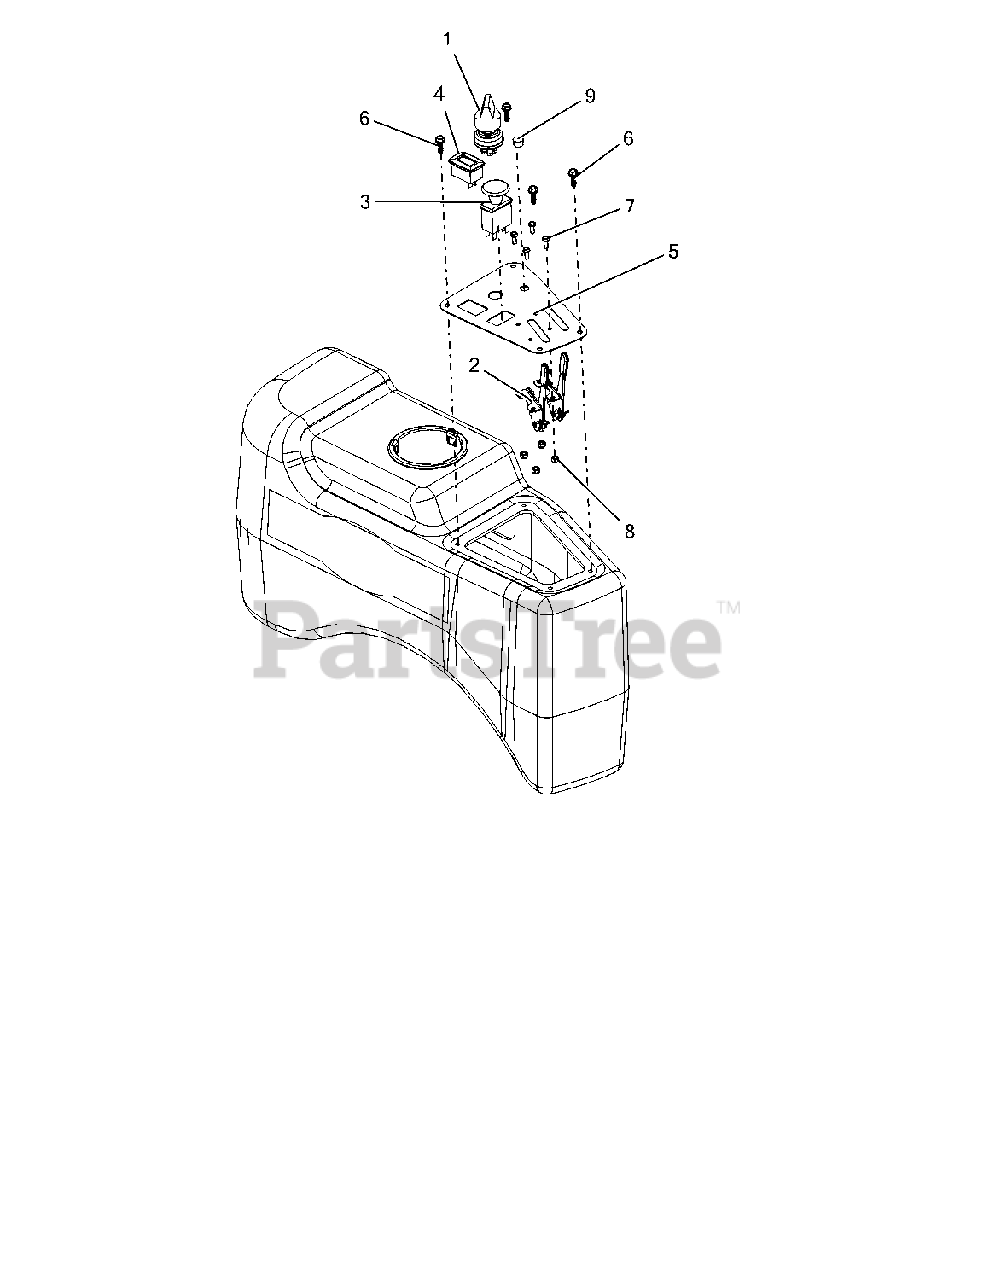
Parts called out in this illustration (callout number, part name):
1	SWITCH, IGNITION
2	CABLE, CONTROL
3	SWITCH, CLUTCH
4	METER, HOUR W/MAINTENANCE
5	PANEL, INSTRUMENT-BLACK
6	SCR-PLASTITE .25-10X.75 YWZC
7	@SCR-MCH 10-24X.50 HWH YWZC
8	NUT-LK-NYL #10-24 YWZC
9	PLUG, HOLE .50 DIA
